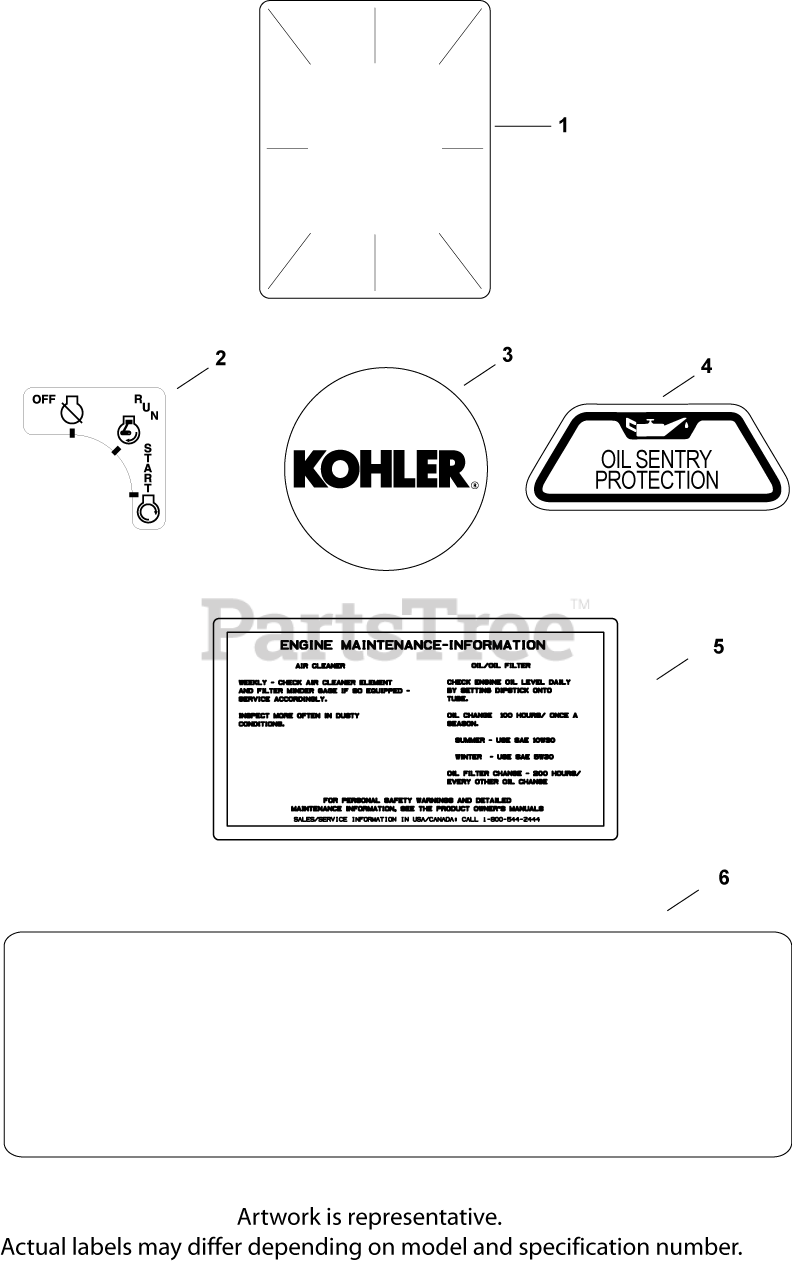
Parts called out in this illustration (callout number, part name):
1	DECAL, CLEAR LAMINATE USE 25 113 70-S
2	DECAL, KEY SWITCH
3	LABEL, (ROUND KOHLER GOLD)-USE 24 113 18
4	DECAL, OIL SENTRY - (#DSC)
5	DECAL, AIR CLEANER - (#DSC)
6	DECAL, 27 HP
